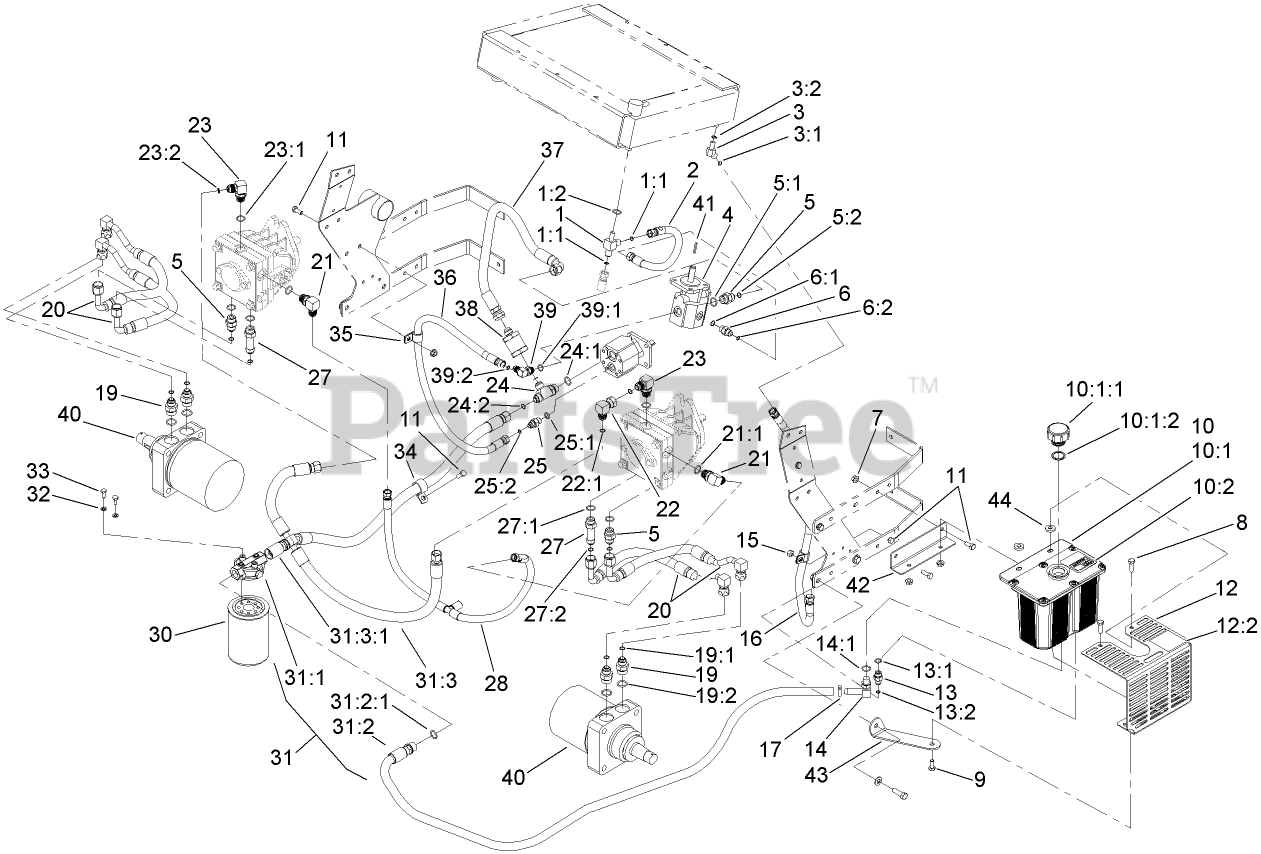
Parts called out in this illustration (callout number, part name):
1	FITTING-HYD, STRAIGHT TEE
1:1	O-RING
1:2	O-RING
2	FAN CASE DRAIN HOSE ASM
3	FITTING-HYD, 45 ELBOW
3:1	O-RING
3:2	O-RING
4	MOTOR-FAN, COOLING
5	FITTING-STRAIGHT
5:1	O-RING
5:2	O-Ring
6	FITTING-STRAIGHT
6:1	O-RING
6:2	O-RING
7	NUT-HF
8	SCREW-HH
9	SCREW-HH
10	HYDRAULIC TANK ASM
10:1	TANK-HYDRAULIC
10:1:1	CAP-RESERVOIR, HYD
10:1:2	GASKET-CAP
10:2	DECAL-TANK, HYD
11	SCREW-HH
12	HYDRO TANK SHIELD ASM
12:2	DECAL-SURFACE, HOT (CE)
13	FITTING-STRAIGHT
13:1	O-Ring
13:2	O-RING
14	FITTING-ELBOW, 90 DEG
14:1	O-RING
15	NUT-LOCK, NI
16	TANK RETURN HOSE ASM
17	CLAMP-HOSE
19	Fitting-Straight
19:1	O-RING
19:2	O-Ring
20	HYD HOSE ASM
21	FITTING-ELBOW, 90 DEG
21:1	O-RING
22	FITTING-90 DEG
22:1	O-Ring
23	FITTING-90 DEG
23:1	O-RING
23:2	O-Ring
24	FITTING-TEE
24:1	O-RING
24:2	O-Ring
25	FITTING-STRAIGHT
25:1	O-Ring
25:2	O-RING
27	ADAPTER-HYD, STRAIGHT
27:1	O-RING
27:2	O-Ring
28	CASE DRAIN HOSE ASM
30	CARTRIDGE-FILTER, OIL
31	CHARGE HOSE ASM
31:1	HEAD-FILTER
31:2	FILTER INLET HOSE ASM
31:2:1	O-RING
31:3	PUMP INLET HOSE ASM
31:3:1	O-RING
32	WASHER-LOCK
33	SCREW-HH
34	CLIP-LOOM
35	CLIP-LOOM
36	AUXILLARY PUMP HOSE ASM
37	HOSE-PRESSURE, HIGH
38	FILTER-IN LINE, 50 MICRON
39	FITTING-90 DEG
39:1	O-Ring
39:2	O-RING
40	MOTOR-WHEEL, HYD
41	KEY-SQUARE
42	BRACKET-TANK MOUNT, UPPER
43	BRACKET-TANK MOUNT, LOWER
44	WASHER-FLAT
